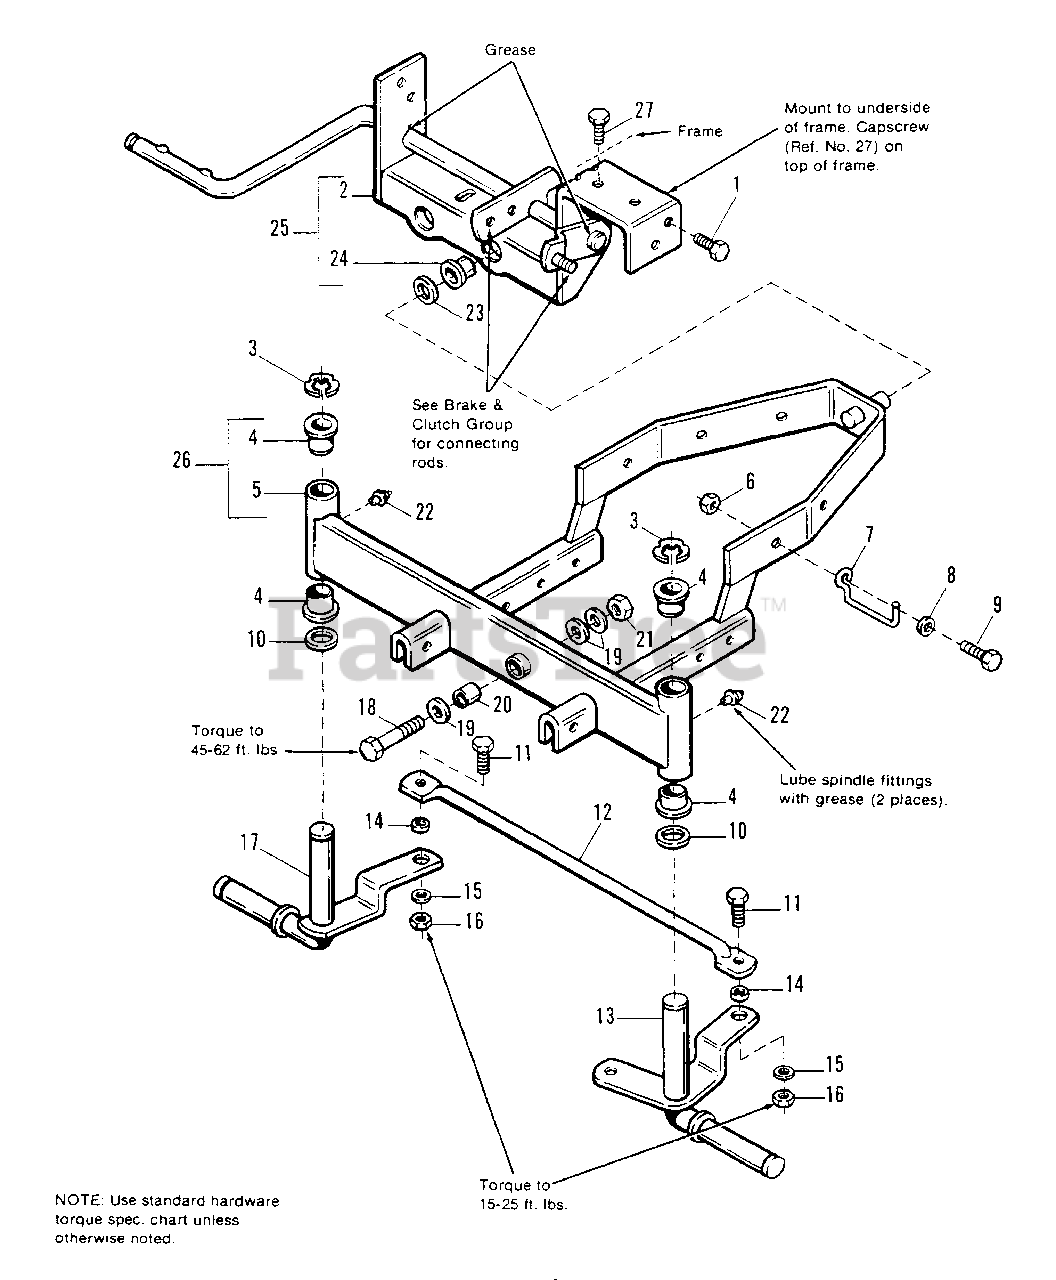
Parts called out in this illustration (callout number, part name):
1	SCREW, Taptite, 5/16-18 x 3/4
3	CLIP, Ring, 3/4
6	NUT, Hex, 5/16-18
7	GUIDE Drag Link
9	CAPSCREW, Hex Hd., 5/16-18 x 1
10	WASHER
11	CAPSCREW, Hex Hd., 3/8-16 x 1
13	SPINDLE ASSY., L.H.
15	WASHER
16	NUT, Hex, Lock, 3/8-16
17	SPINDLE ASSY., R.H.
18	CAPSCREW, Hex Hd., 1/2-13 x 2-1/4, Gr. 8
21	NUT, Hex Lock, 1/2-13
22	FITTING, Grease
25	SUPPORT ASSY., Brake/Clutch (Incl. Ref. Nos. 2 & 24)
26	AXLE ASSY., Front (Incl. Ref. Nos. 4 & 5)
27	CAPSCREW, 5/16-18 x 3/8
